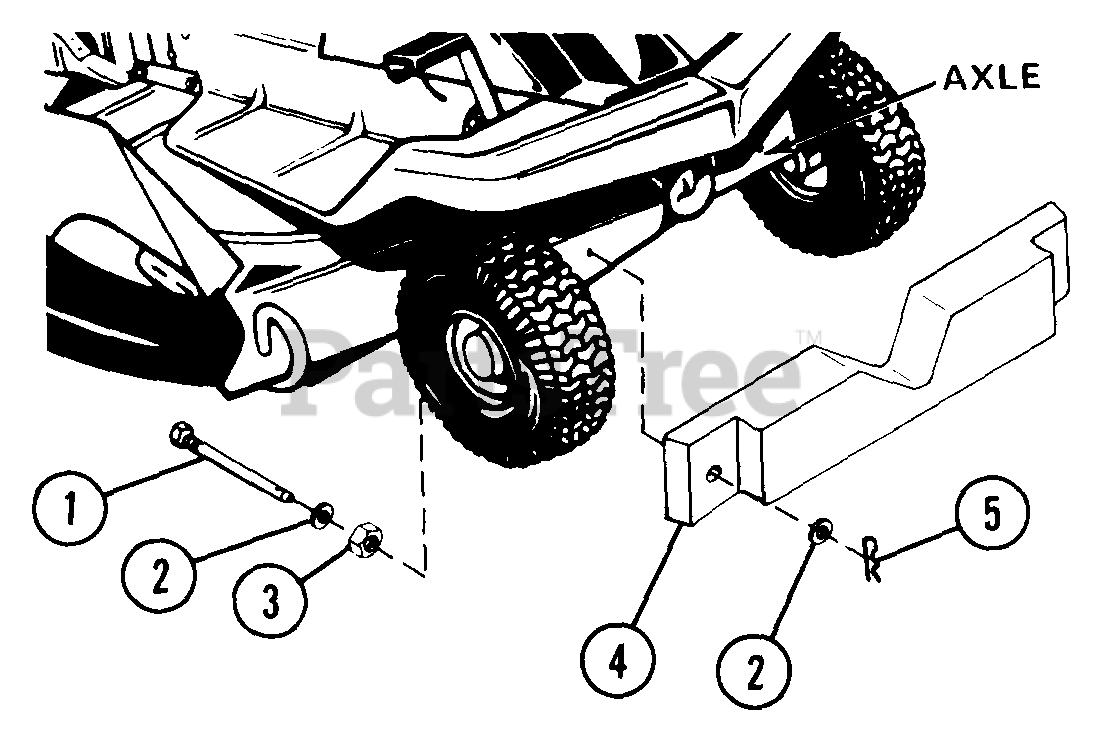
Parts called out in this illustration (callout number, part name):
1	STUD-WEIGHT
2	WSHR-FL-STL .511X1.441X.125 PL
3	NUT-LK-CTR .50-13
4	WEIGHT KIT REAR CATCHER
5	PIN-HAIR INT .09X.188 PL
